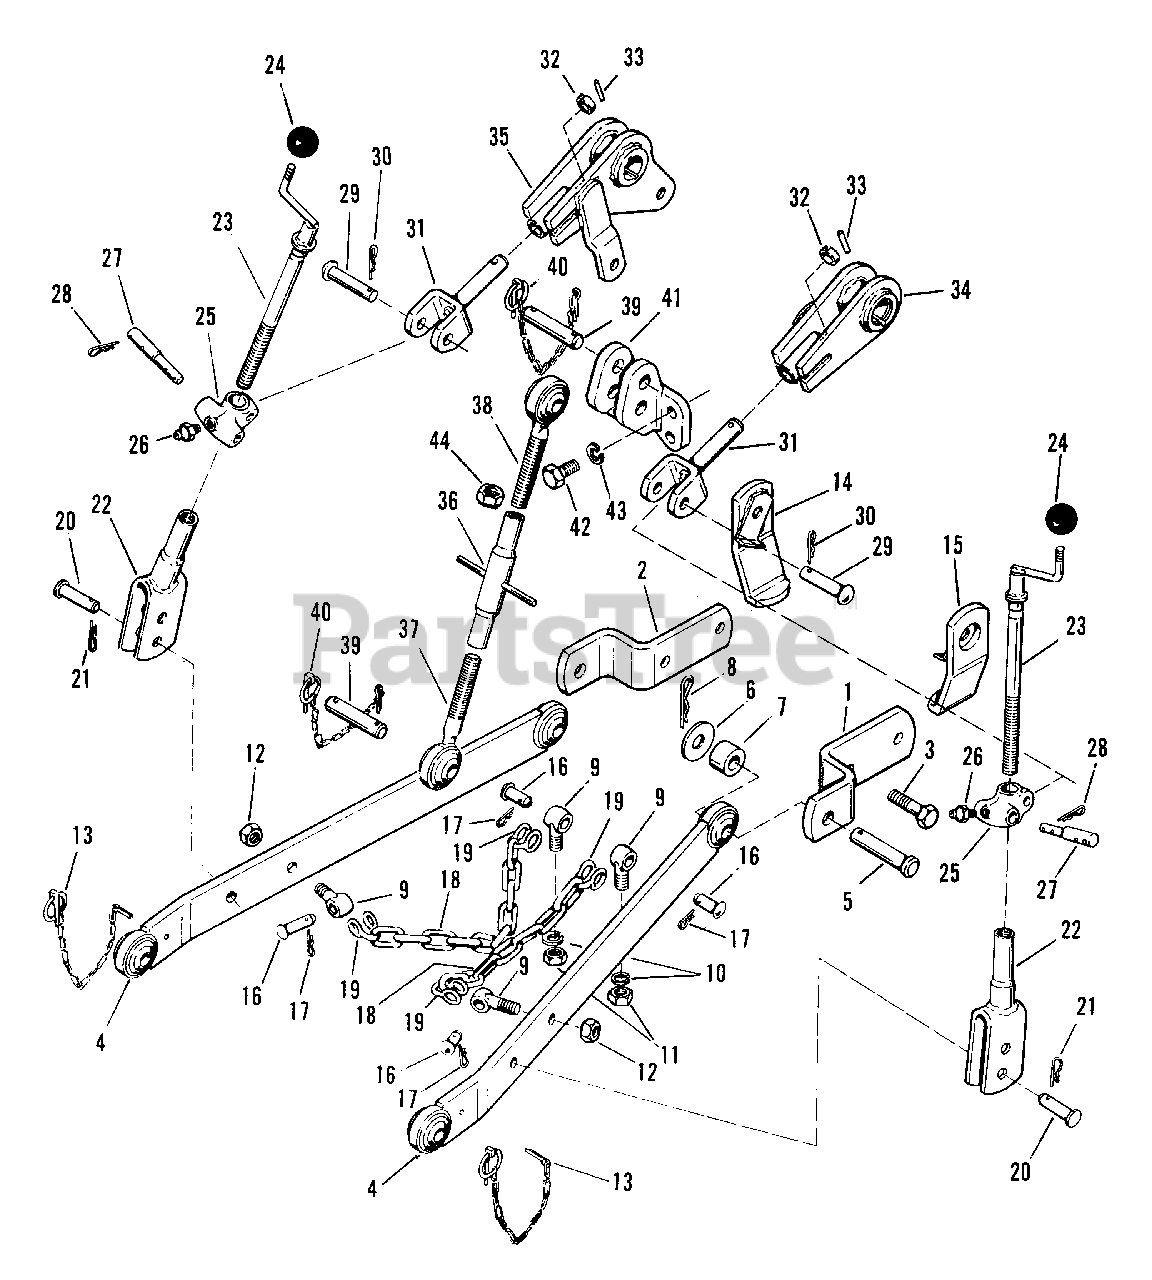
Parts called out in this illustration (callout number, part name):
1	Pull Link Strap, R.H.
2	Pull Link Strap, L.H.
3	Hex Capscrew, 1/2"-13 x 2" lg.
4	Pull Link Assembly
8	Hairpin Clip
9	Eyebolt, 1/2"-20
10	Lock Washer, 1/2"
11	Hex Nut, 1/2"-20
12	Hex Nut, Center Lock 1/2"-20
13	Retaining Pin
14	Rub Bar Assembly, L.H.
15	Rub Bar Assembly, R.H.
17	Hairpin Clip
21	Hairpin Clip
22	Clevis Assembly
23	Link Assembly
26	Grease Fitting
28	Hairpin Clip
30	Hairpin Clip
31	Clevis Assembly
34	Lift Arm Assembly, R.H.
35	Lift Arm Assembly, L.H.
36	Upper Link Assembly
37	Stud Assembly, R.H.
38	Stud Assembly, L.H.
40	Retaining Pin
41	Upper Link Support
42	Hex Capscrew, 7/16"-14 x 1-1/4" lg.
43	Lock Washer, 7/16"
44	Hex Nut, 3/4"-10 L.H.
